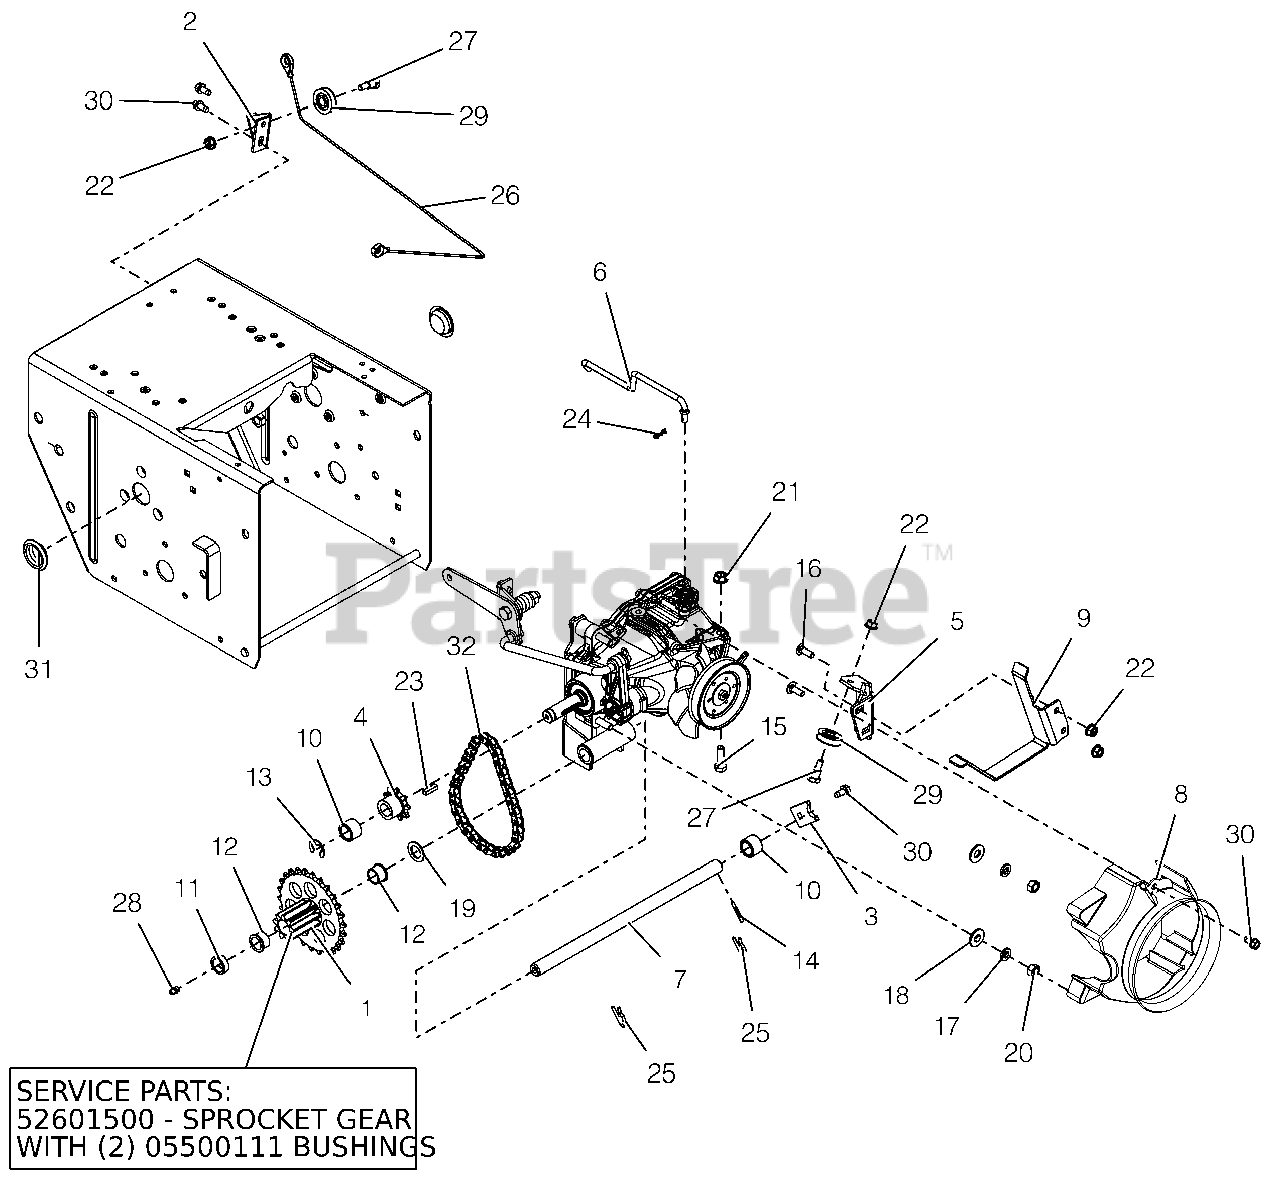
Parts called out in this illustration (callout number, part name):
1	PINION & SPROCKET
1	PINION & SPROCKET W/BUSHINGS
1	BSHG-FLG .625X.750X.500X.875
2	BRACKET, CABLE PULLEY
3	TAB, ANTI ROTATION
4	SPROCKET, PINION 9T W/KEY
5	BRACKET, CLUTCH CABLE
6	ROD, HYDRO BYPASS
7	SHAFT, PINION - HARDENED
8	SHROUD, HYDROGEAR RT-310
9	FINGER, BELT - FLAT
10	SPACER, .635X.880X.611
11	BSHG-SLV, .635X.880X.305
12	BSHG-FLG .625X.750X.500X.875
13	RG-RTNG-EXT .625X.042
14	PIN-GRV .125X1.00 TP E ALLOY
15	@BLT-HEX .31-18X1.00 GR5 YWZC
16	@BLT-RDHDSQNK .25-20X.75 G5YZ
17	WSHR-LK .312X.097 HVY YWZC
18	@WSHR-FL-STL.38X.875X.083 YWZC
19	WSHR-FL-STL .630X1.005X.062 YZ
20	@NUT-HEX .31-18 YWZC
21	@NUT-LK-TOP-FLG .31-18 YWZC
22	@NUT-LK-TOP-FLG .25-20 YWZC
23	KEY-SQ .188X.75X.188
24	PIN-HAIR INT .06X.18X.77
25	PIN, SPRING CLIP
26	CABLE, TRACTION, HYDRO PRO
27	BOLT, SHLDR-.375X.375X.25-20
28	ZERK,FITTING .25X.125 DRIVE IN
29	PULLEY, CABLE
30	SCR-TAP .25-20X.50 HWH TR YWZ
31	PLUG, HOLE - 1.125"
32	CHAIN - #41, 32 PITCHES
